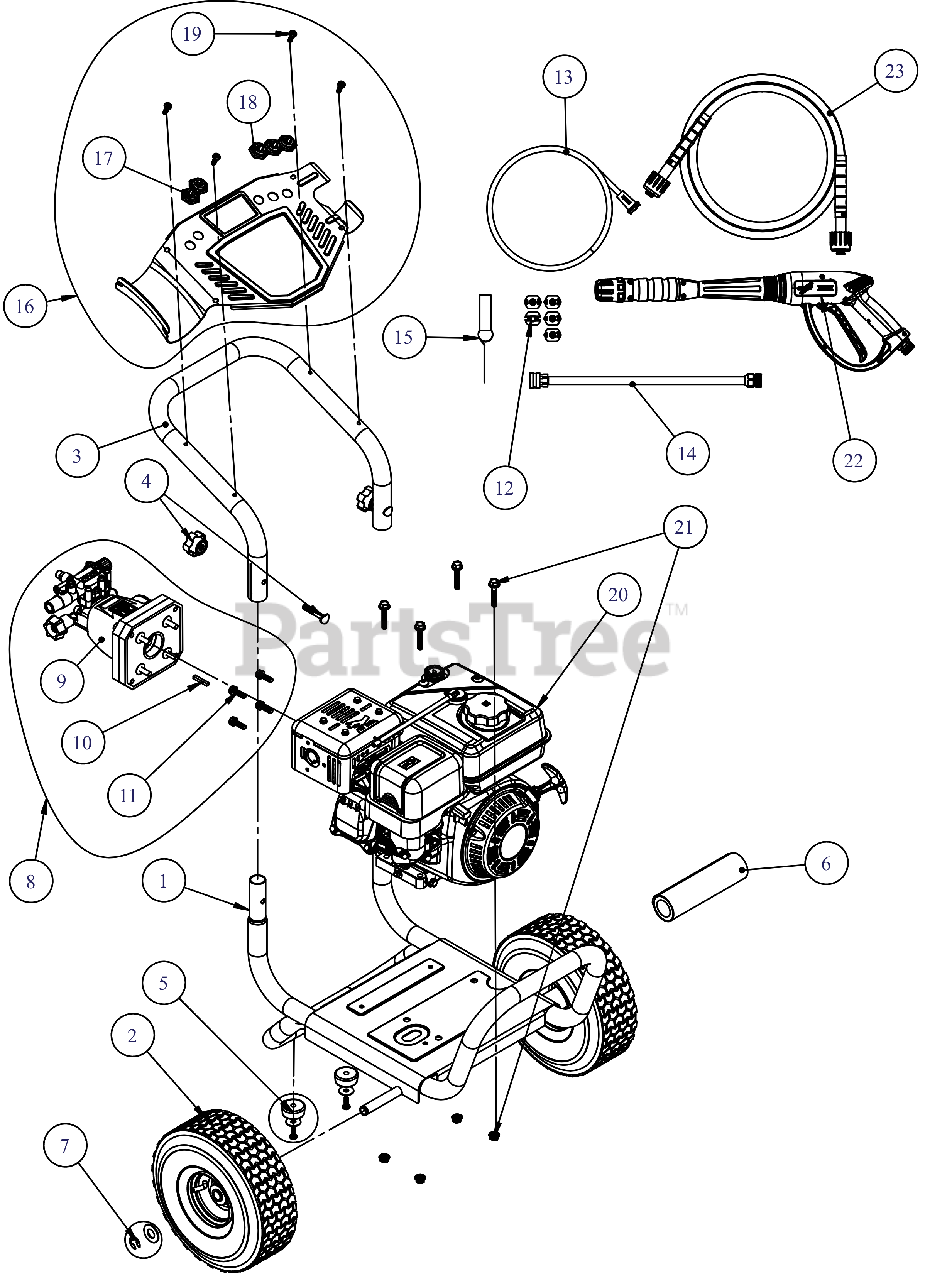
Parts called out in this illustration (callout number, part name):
1	BASE ASSEMBLY-FRAME
2	WHEEL ASSEMBLY
3	UPPER HANDLE
4	KNOB-HANDLE MTG
6	GRIP-HANDLE
7	WHEEL MOUNTING KIT
9	AX300 PUMP
10	SHAFT KEY (3/16x3/16x1.25)
11	HARDWARE KIT: PUMP MOUNTING
12	5 PIECE NOZZLE SET
13	HOSE-SOAP W/FILTER
14	WAND-SPRAY GUN 16"
15	TOOL-NOZZLE CLEANING
16	DASHBOARD PANEL (W/LABEL CC 3400)
17	HOLDER-NOZZLE 2 PC
18	HOLDER-NOZZLE 3 PC
19	DASHBOARD MOUNTING KIT (4-SCREWS)
20	COMPLETE ENGINE 208cc
21	MOUNTING KIT: ENGINE
22	SPRAY GUN (3600PSI M22)
23	MORFLEX HOSE (5/16 x 25')
